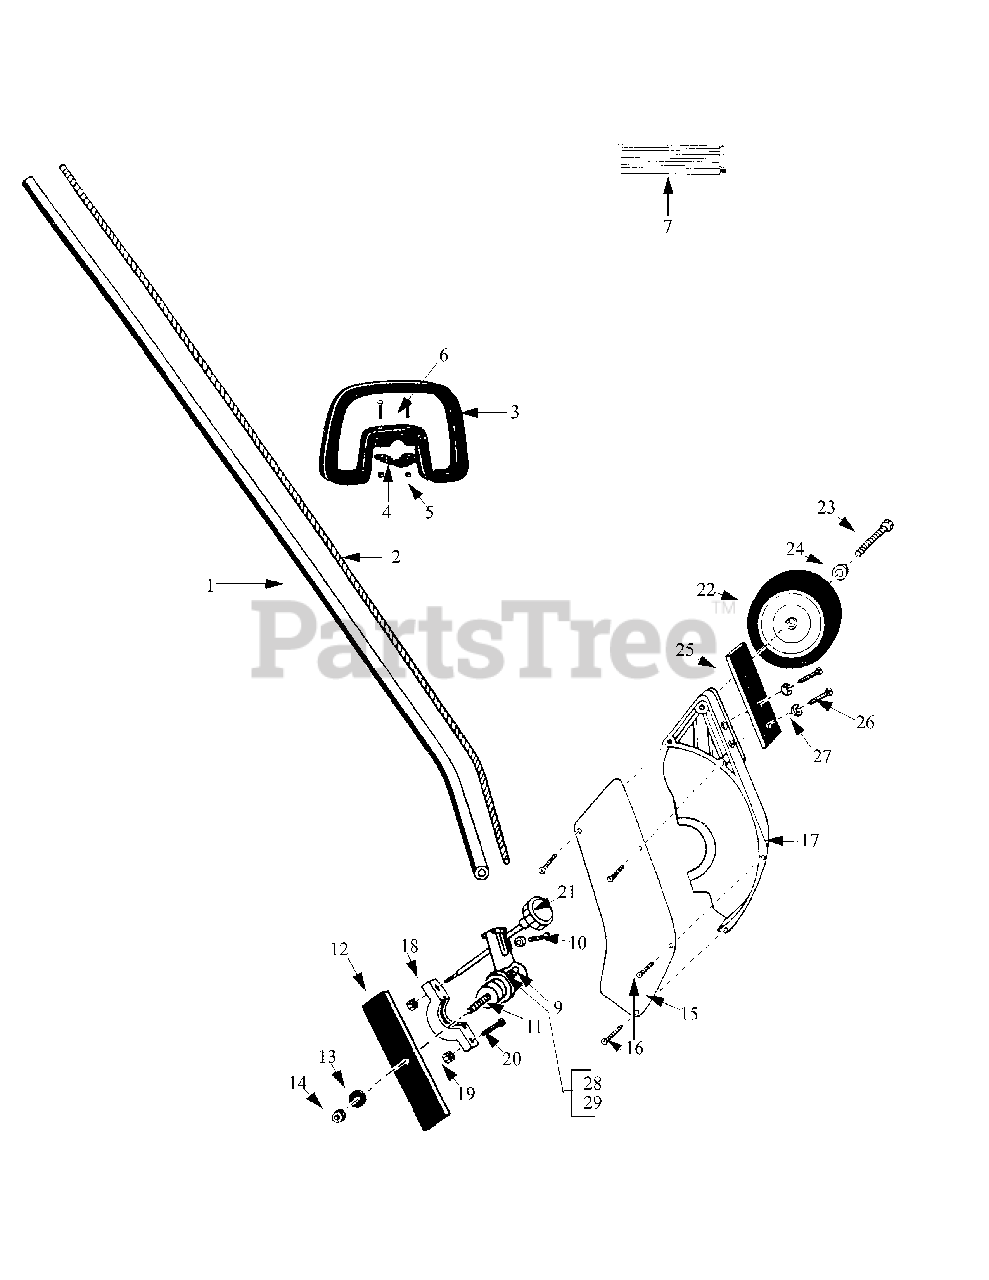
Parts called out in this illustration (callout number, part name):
1	Drive Shaft Housing
2	Flexible Drive Shaft
4	Handle Clamp
5	Nut, Nylock 1/4-20
6	Screw, 1/4-20x1-3/4
9	Gear Head Assembly
10	Screw Kit
11	Cup Washer
13	Washer, Blade
14	L.H. Nut, 10mm
15	Side Plate
16	Screw, #8-32X1/2
17	Blade Guard
18	Blade Guard Bottom
19	Nut, Nylock 1/4-20
20	Socket Head Cap Screw 1/4-20x1"
21	Adjustment Knob
23	Bolt, shoulder
25	Debris Flap
26	Screw #10-24X5/8
27	Washer No. 10
28	Grease Plug
29	Hex Head Bolt-grease plug
